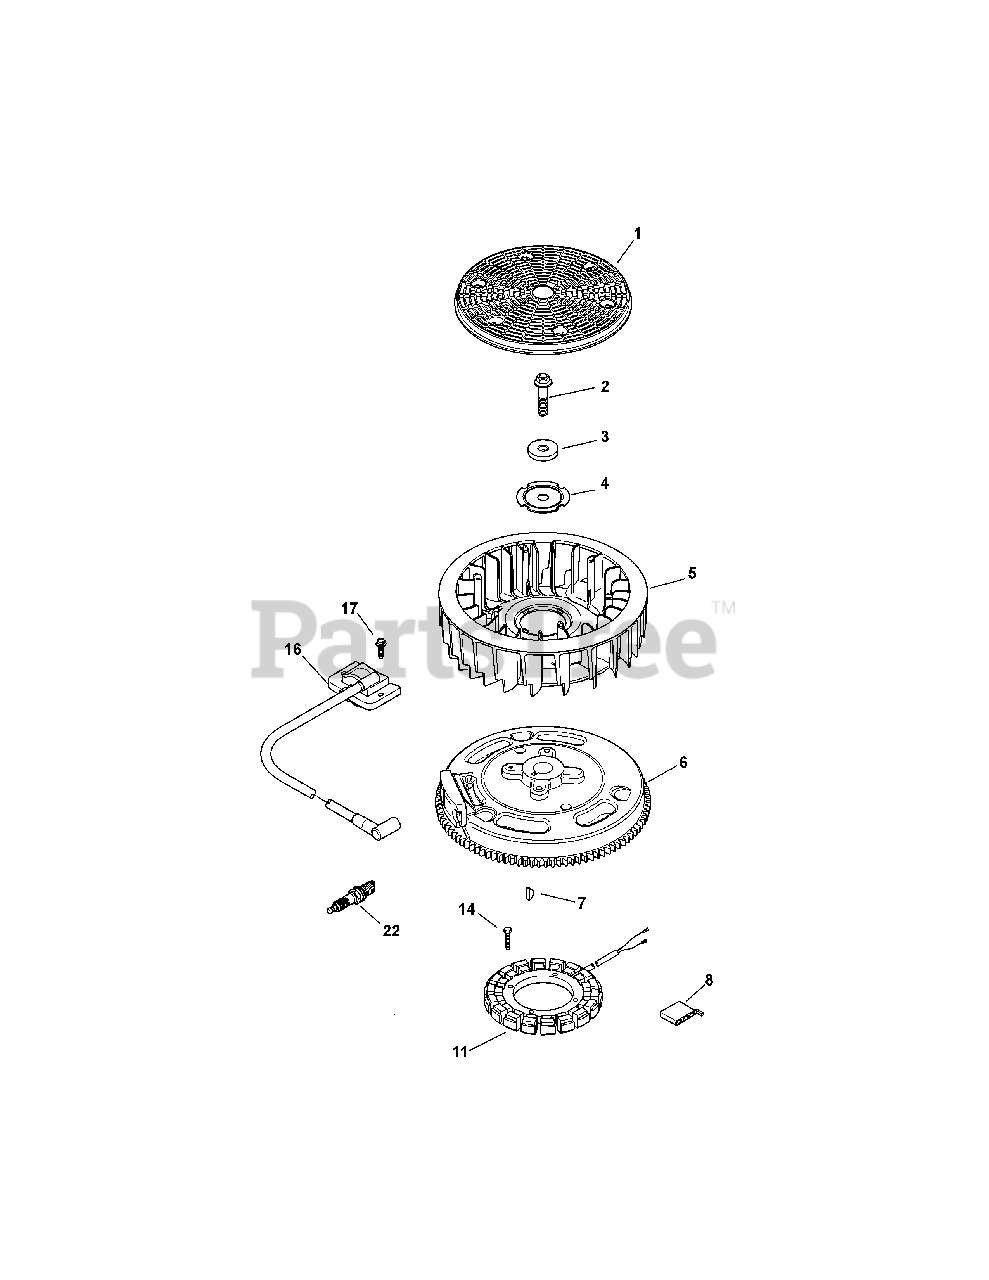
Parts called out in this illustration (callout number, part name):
2	Flg. Screw, M 10 X 1.5 X 45
3	Flat Washer, 13/32
4	Fan Mounting Plate
5	Fan
6	Flywheel Assembly
7	Key, 3/16 X 5/8
11	15 Amp Stator Kit (Inc. KH-25-452-01-S)
14	Thd. Frm. Screw, M5 X 0.8 X 25
16	Module Ignition Kit
17	Flg. Thd. Frm. Screw, M5 X .8 X 20
22	Spark Plug
